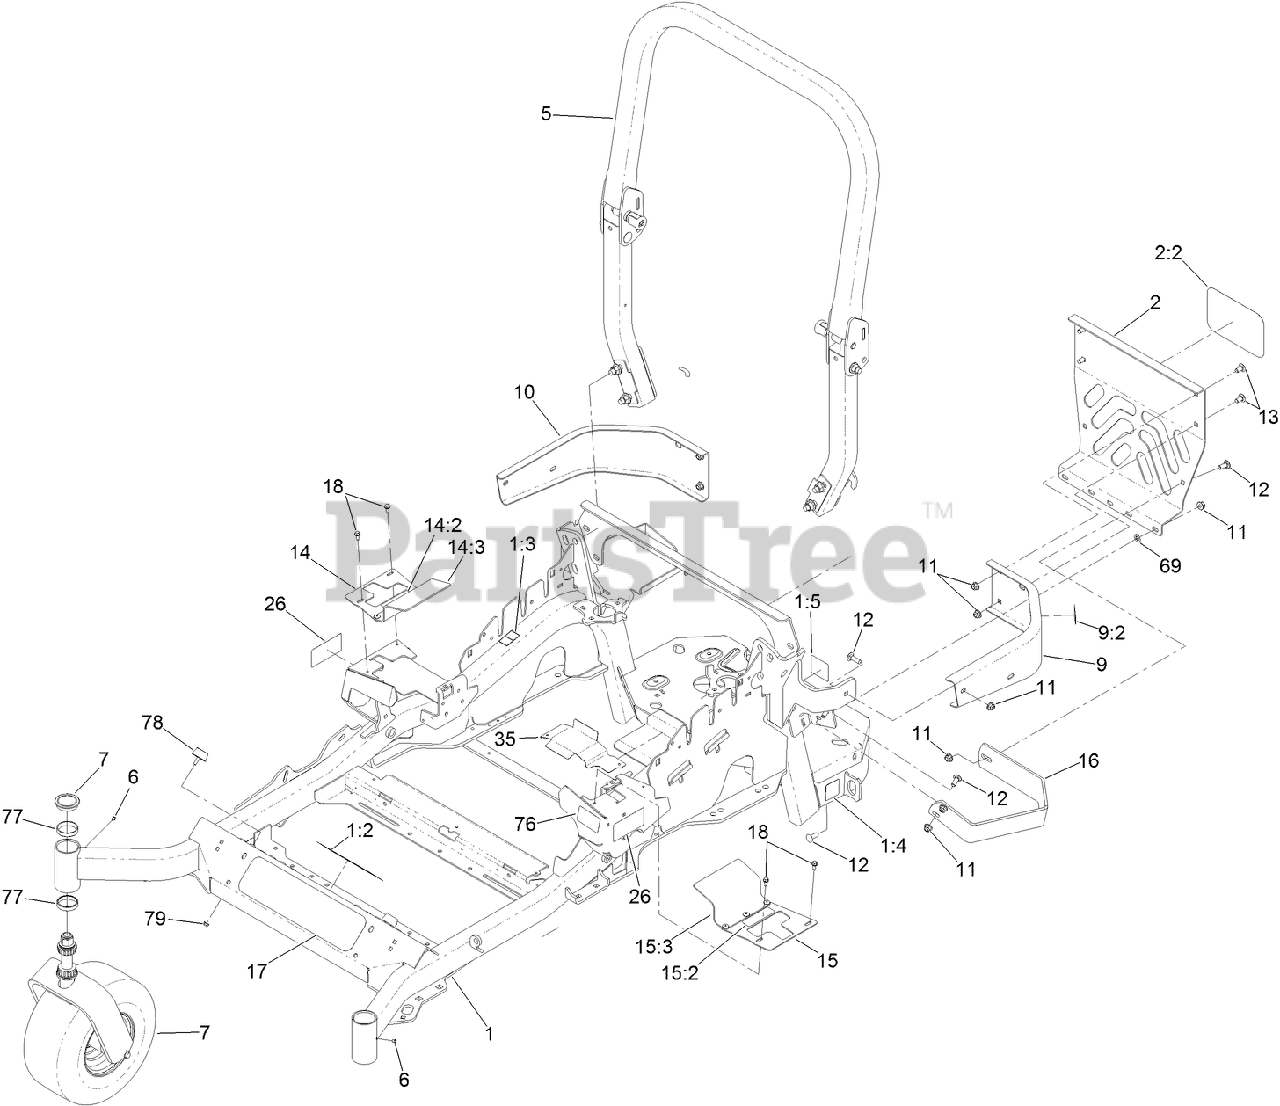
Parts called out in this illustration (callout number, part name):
1	MAINFRAME ASM
1:2	DECAL-DANGER
1:3	DECAL-WARNING
1:4	DECAL-HAZARD, PINCHED FINGER
1:5	DECAL-SPARK ARRESTER
2	REAR GUARD ASM
2:2	DECAL
5	ROPS ASM
7	Caster Wheel ASM
9	LH BUMPER ASM
9:2	DECAL-WARNING
10	BUMPER-RH
11	NUT-HF, NI
12	SCREW-CARR
13	SCREW-CARR
14	RH MOTION CONTROL COVER ASM
14:2	DECAL-CONTROL, MOTION
14:3	FLAP-RUBBER
15	LH MOTION CONTROL COVER ASM
15:2	DECAL-CONTROL, MOTION
15:3	FLAP-RUBBER
16	GUARD-MUFFLER
17	DECAL-Z MASTER, COMMERCIAL
18	SCREW-HWH
35	GUARD-BELT
69	NUT-PUSH
76	DECAL-FUEL FILL, CE
77	CUP-BEARING
78	BUMPER
79	NUT-HF
